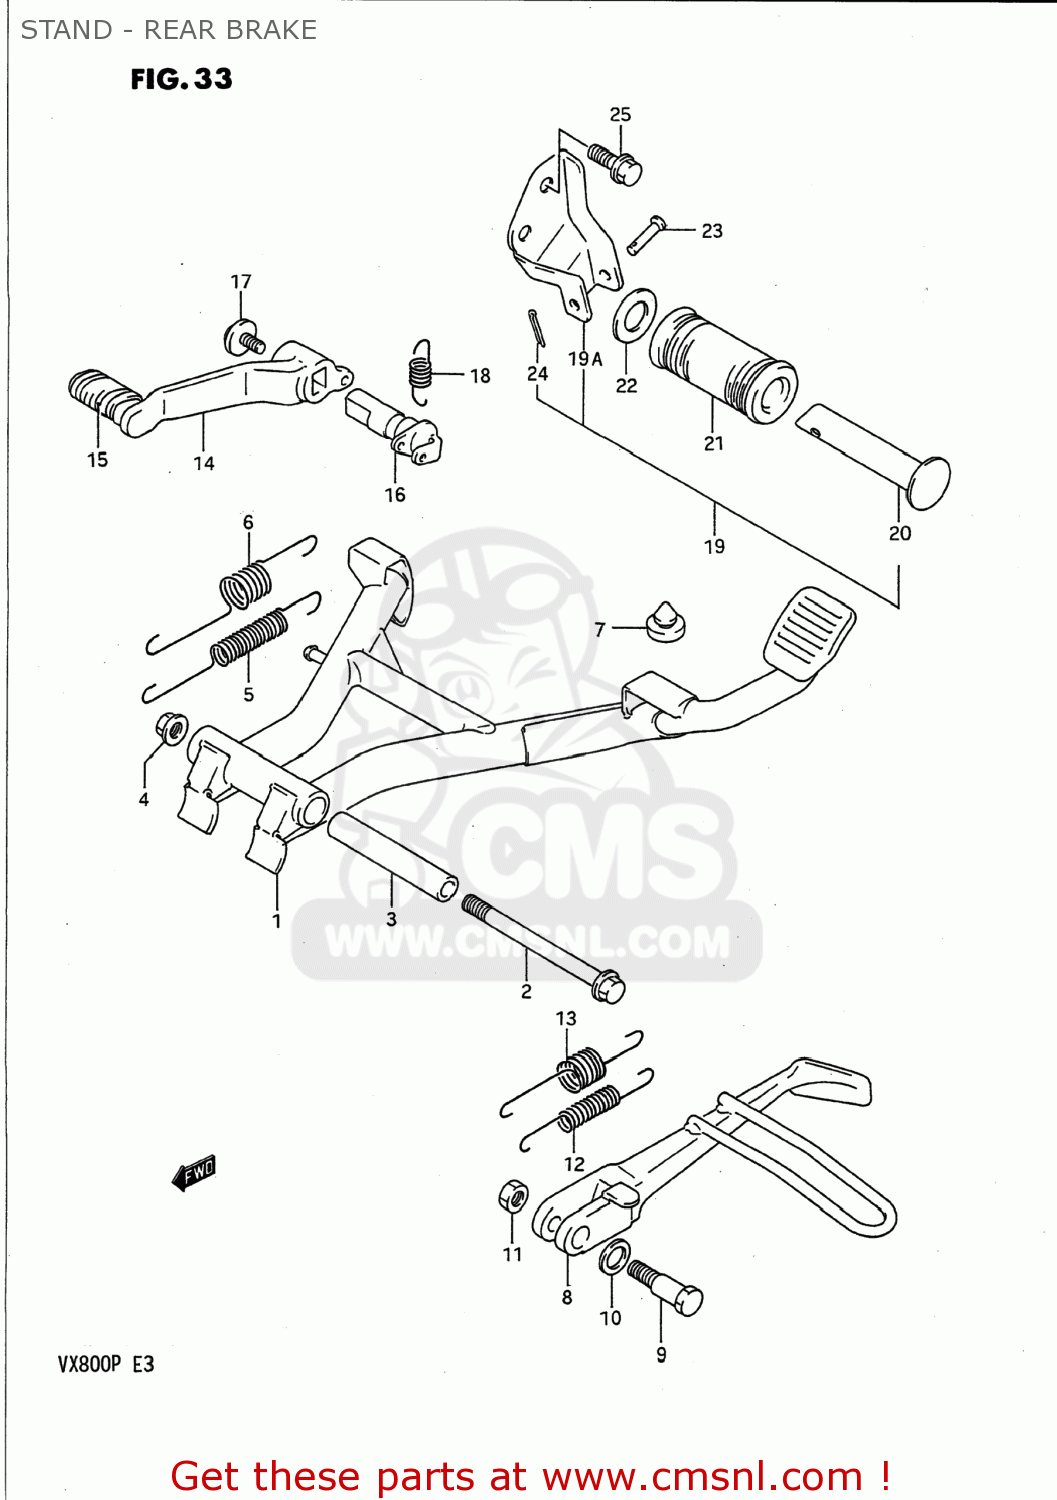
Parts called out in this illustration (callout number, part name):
1	STAND,CTR
2	BOLT(10X115)
3	SPACER,CENTER STAND
4	NUT
5	SPRING,CENTER STAND,INNER
6	SPRING,CENTER STAND,OUTER
7	CUSHION
8	STAND,SIDE
9	BOLT(10X38)
10	SHIM
11	NUT
12	SPRING,PROP STAND,INNER
13	SPRING
14	PEDAL,BRAKE
15	RUBBER,PEDAL
16	ARM,BRAKE PEDAL
17	BOLT(8X14)
18	SPRING,BRAKE PEDAL
19	GRIP SET,CTR STAND
19A	HOLDER COMP,CENTER STAND
20	BAR,PILLION FOOTREST
21	RUBBER,STAND GRIOP (OPT)
22	WASHER (19.5X32X2)
23	PIN
24	PIN
25	BOLT, LOWER
